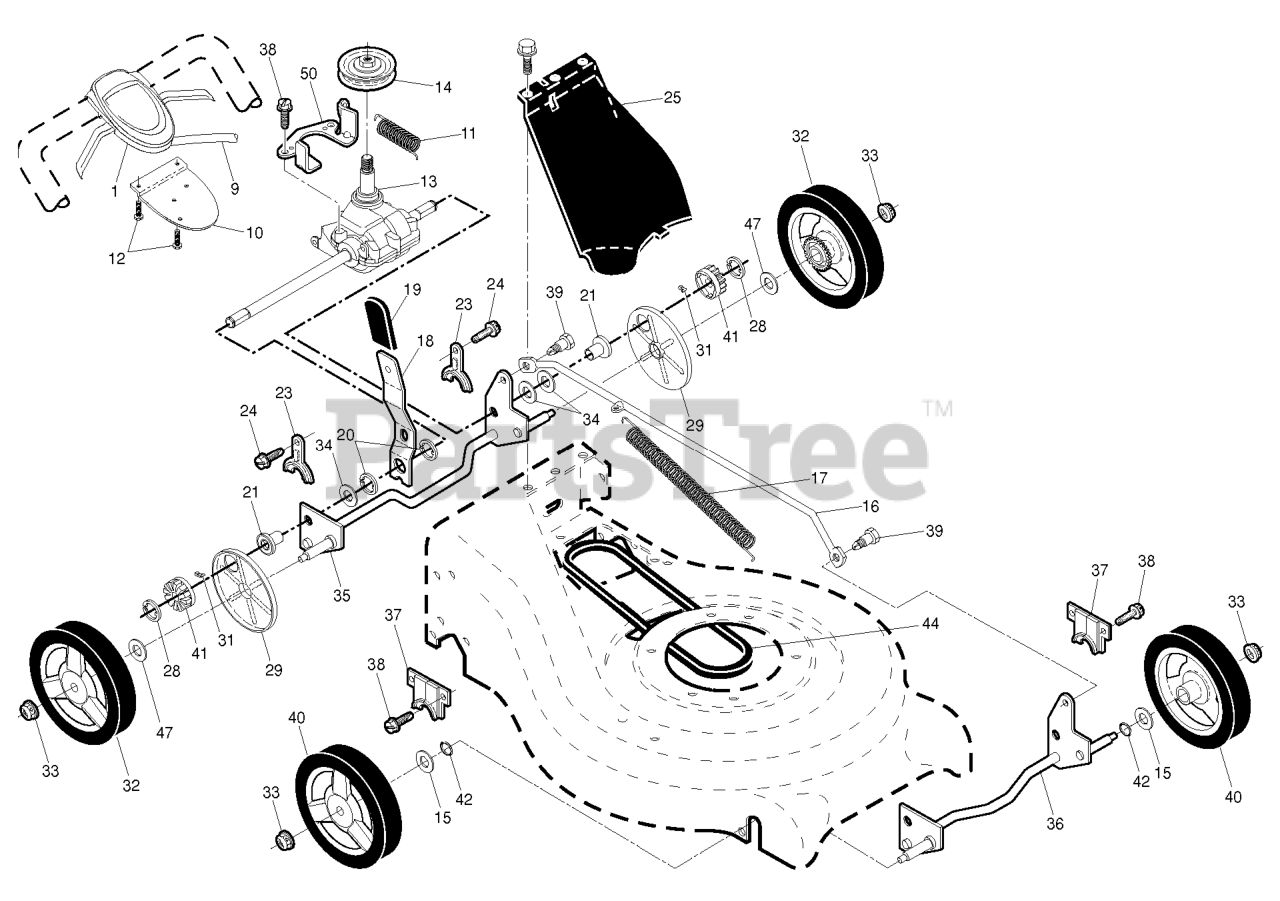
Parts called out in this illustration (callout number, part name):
1	RP.CONTROL.AW2.21RGD.BS.GR/BLK
9	CABLE.CONTROL.21RGD
10	BRACKET.DRIVE.CONTR.GEN2.BLACK
12	SCREW, PHILLIPS HEAD 10 X 5/8
13	TRANSMISSION.21.RWGD
14	PULLEY.1.PIECE
15	WASHER.FLAT.1/2
16	ROD.CONNECTING.SPT.BLACK
17	SPRING EXTENSION
18	SPRING.SELECTOR.
19	KNOB.EXT.ERGO.BLACK
21	BEARING.ASM.RGD.AUTO.SP
23	BRACKET
24	SCREW 14-20 X 5/8
25	Drive Cover Assembly
28	E-RING 7/16 RE
29	COVER.DUST.WHEEL.INNER.WALK
31	PAWL, DRIVE
32	WHEEL.8X1.75.3SPK.RAD3.GREY
33	NUT.HEX.FLANGE.3/8-16.LO(3 2)
35	SHAFT ASSY REAR
36	SHAFT ASSY, FRONT
37	RETAINER.FRONT.SHAFT
39	SHOULDER BOLT SEMI GIMLET PT.
40	WHEEL & TIRES ASSY, FRONT
41	PINIION.14.TOOTH.RGD
42	O-RING..070X.487.NEOPRENE
44	BELT.RGD.VS
47	WASHER FLUT
50	BELT KEEPER
